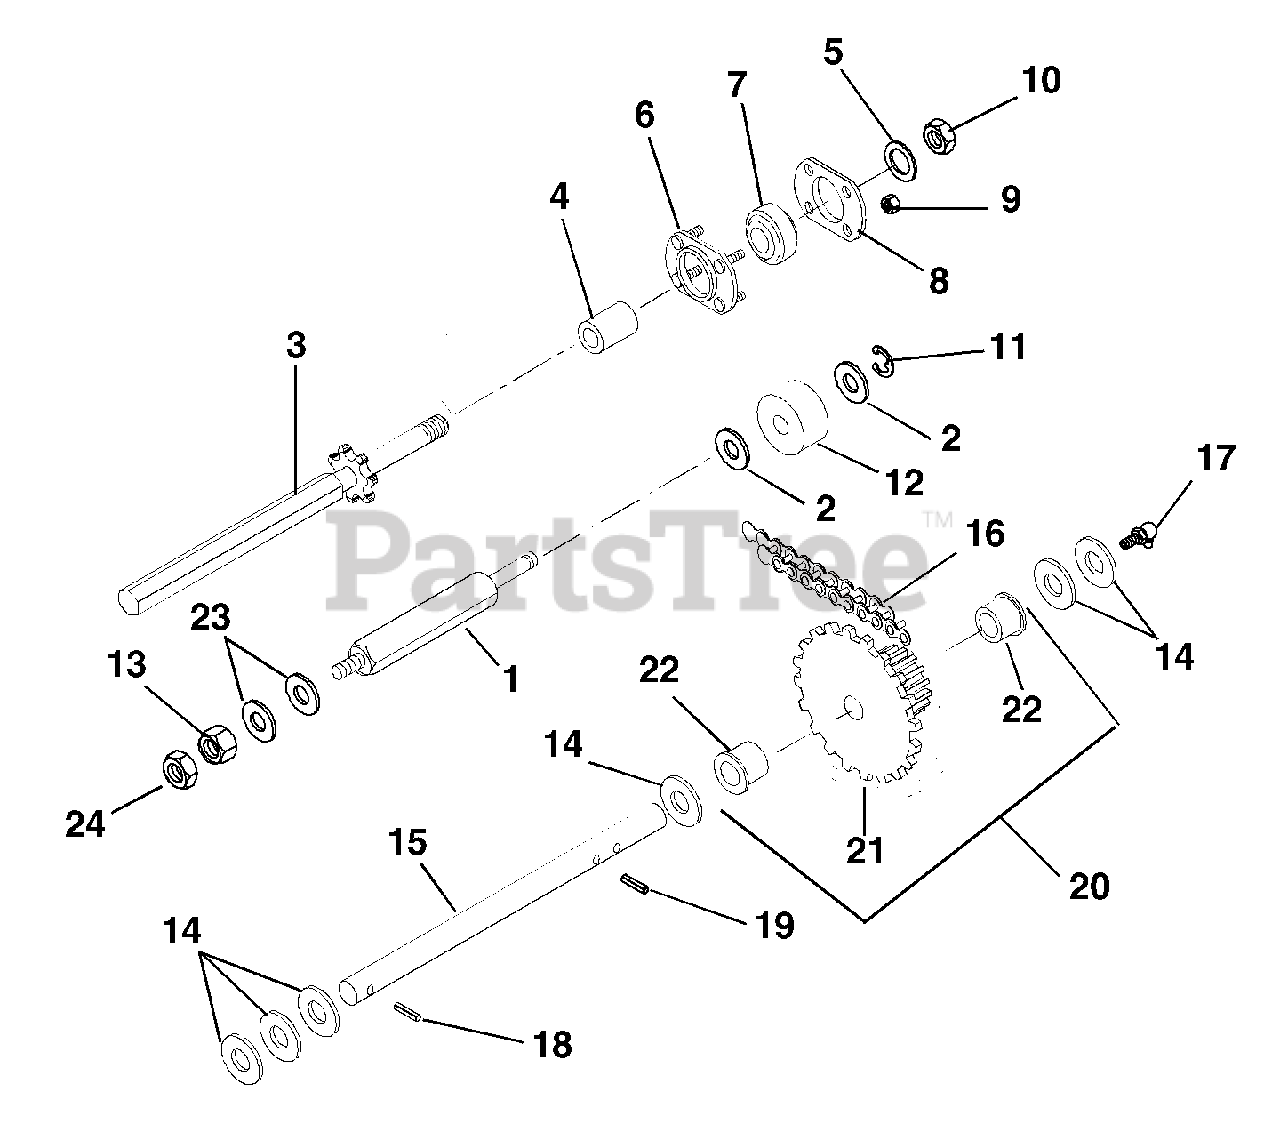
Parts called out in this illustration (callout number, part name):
1	SHAFT, HEX
2	@WSHR-FL-STL.344X.688X.065YWZC
3	SHAFT, HEX - W/SPROCKET
4	BSHG-SLV .450X.750X1.600
5	WSHR-FL-STL .505X.880X.072 YWZ
6	BEARING FLANGE
7	BRG-BALL .437X1.375X.437
8	BEARING FLANGE
9	NUT-LK-DUAL FACE 10-24 YWZC
10	@NUT-LK-CTR .44-14 YWZC
11	RG-RTNG-EXT. .31X.025
12	IDLER 1.38 OD X .31 ID X .69
13	@NUT-LK-CTR .31-18 YWZC
14	WSHR-FL-STL .630X1.005X.062 YZ
15	PINION SHAFT
16	ROLLER CHAIN #41 - 34 PITCHES
17	DRIVE FITTING, HYD. BRIGHT ZC
18	PIN-ROLL .156X1.00
19	PIN-ROLL .125X1.00
20	PINION & SPROCKET ASSEMBLY
21	PINION & SPROCKET
22	BSHG-FLG .625X.750X.500X.875BR
23	@WSHR-FL-STL.38X.875X.083 YWZC
24	NUT- JAM .312-18 YWZC
